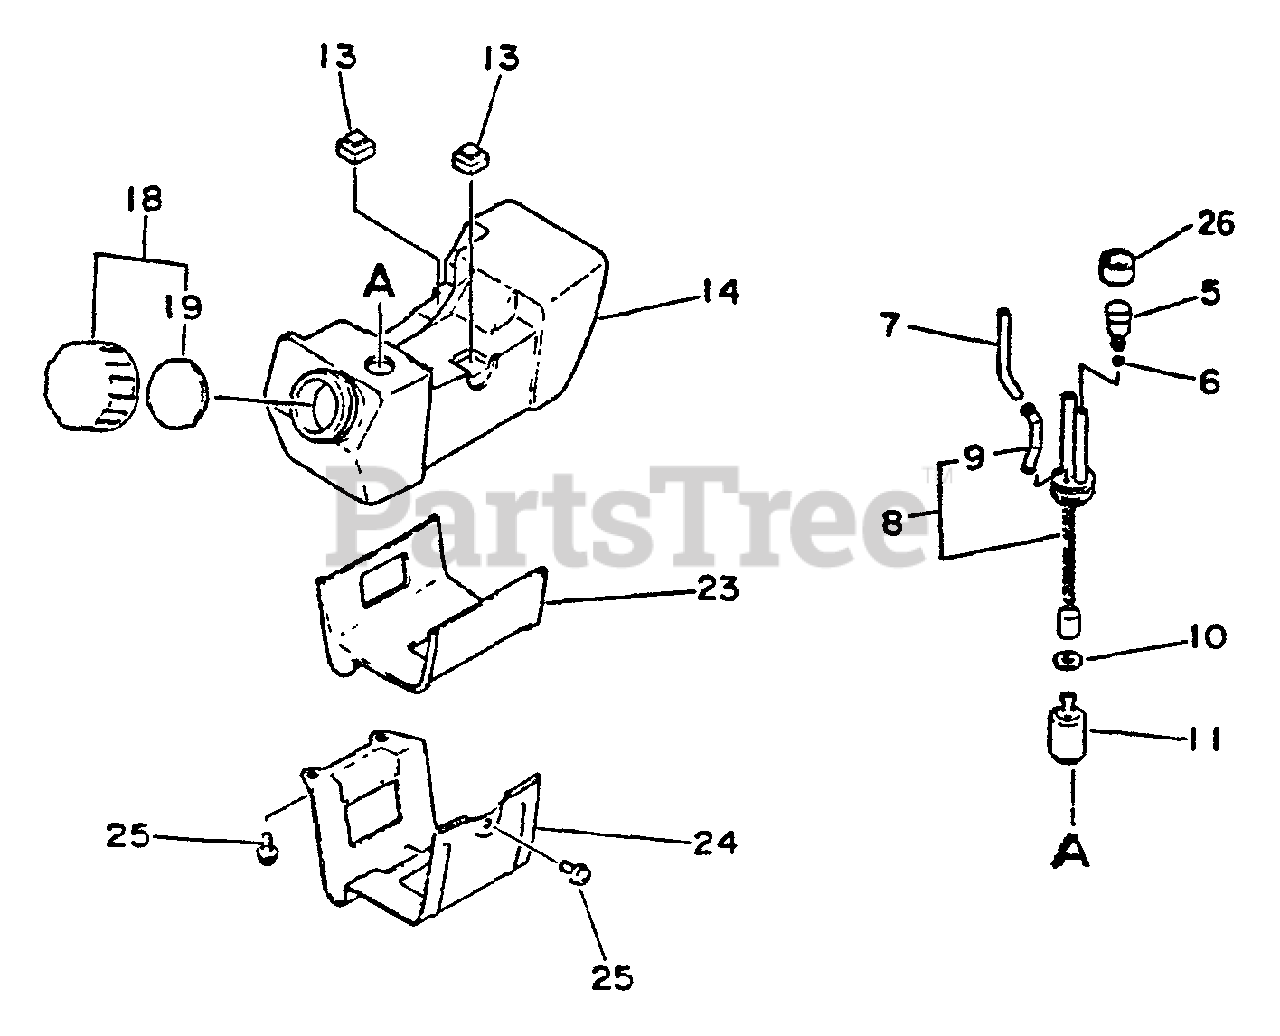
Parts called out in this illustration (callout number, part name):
5	VENT ASSY
7	PIPE, FUEL 3×6×45
8	PIPE, FUEL
9	CONNECTOR, PIPE
10	WASHER 5.5×12×0.8
11	FILTER, FUEL
13	CUSHION
14	TANK, FUEL
18	CAP ASSY
19	GASKET, FUEL CAP
23	CUSHION
24	GUARD, FUEL TANK
25	SCREW 5×10
26	HOLDER, VENT
